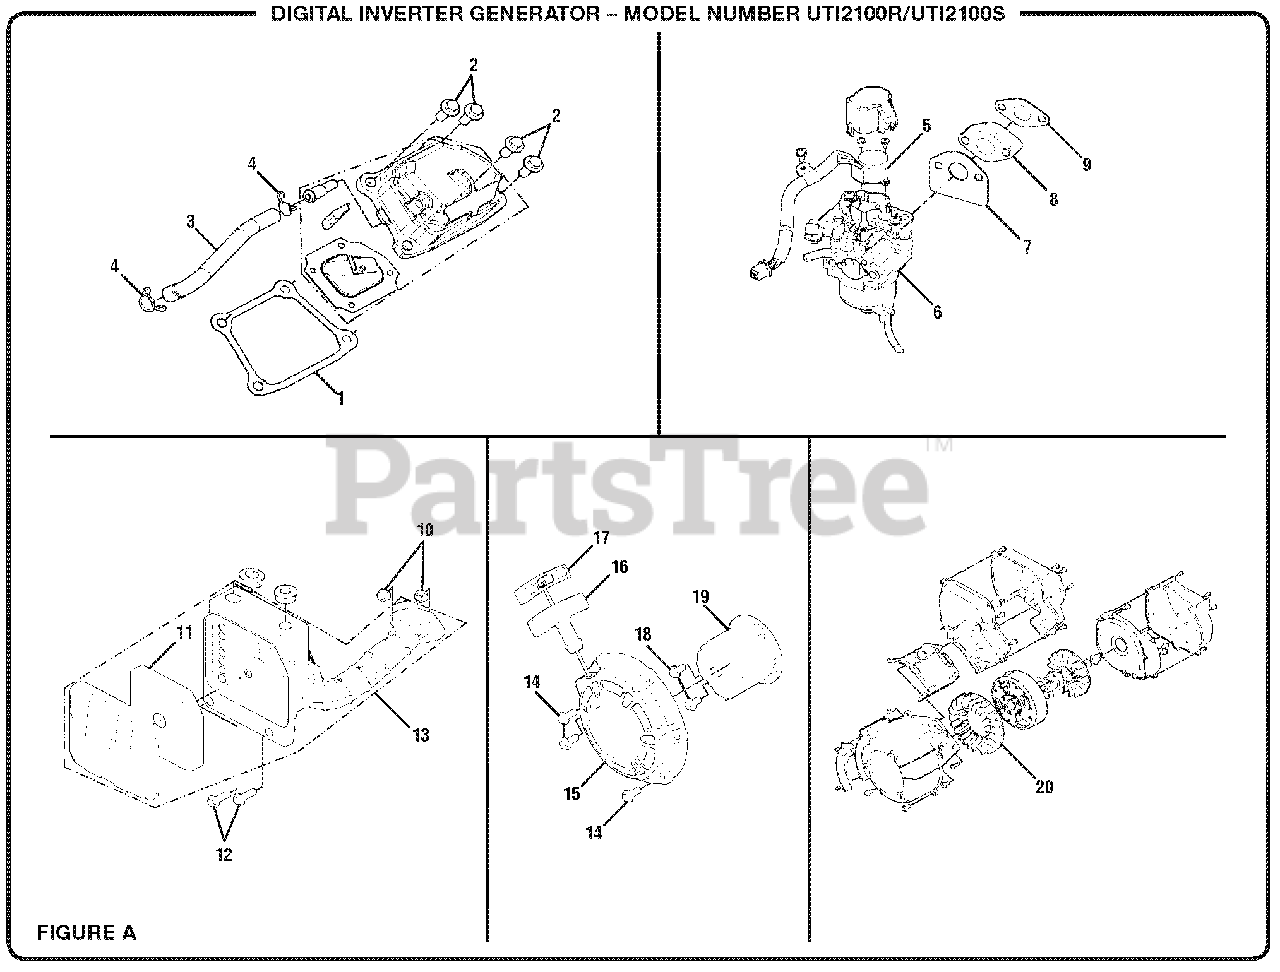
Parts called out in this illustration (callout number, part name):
1	Cylinder Head Cover Gasket
2	Bolt (M6 x 16 mm, Flange Hd.)
3	Engine Vent Hose
4	Clip (M10)
5	Stepper Motor Assembly
6	Carburetor Assembly
7	Intake Seat Gasket
8	Carburetor Seat Adapter
9	Adapter Rear Gasket
10	Flange Nut (M6)
11	Air Filter Element
12	Bolt (M6 x 12 mm, Flange Hd.)
13	Air Filter Assembly
14	Bolt (M6 x 16 mm, Flange Hd.)
15	Recoil Starter Disc Set
16	Recoil Handle
17	Recoil Handle Cover
18	Bolt (M6 x 12 mm, Flange Hd.)
19	Recoil Starter Driving Disc
20	Front Fan
